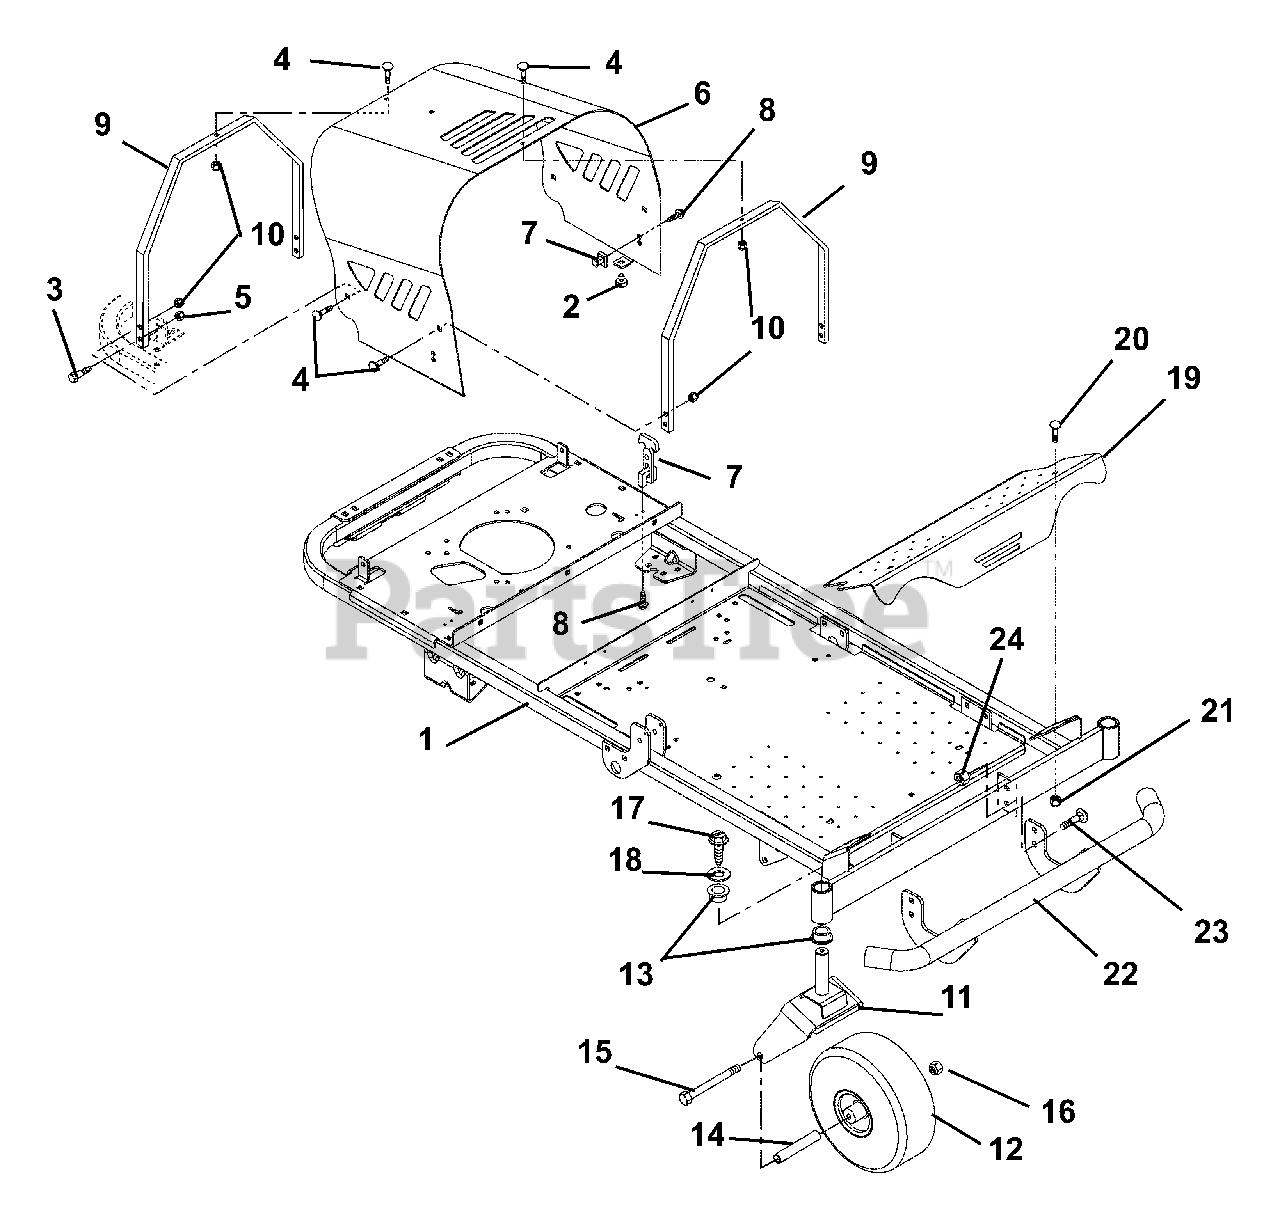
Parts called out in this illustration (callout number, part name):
1	Weldment, Fixed Axle Frame
2	Button Bumper
3	Bolt, Shoulder .375-16 x .135
4	Bolt, Round Head Square Neck .31-18 x .62
5	Nut, Locking Top Flange .38-16
6	Hood, Zoom
7	Latch, Rubber
8	Screw-Machine 10-24 x .50 Hex Washer Head
9	Brace, Hood
10	Nut, Locking Top Flange .31-18
11	Fork, Caster
12	Assembly, Tire 4 x 11- 2 Ply
13	Bushing, Flange 1.00 x 1.25 x 1.50 x 1.50
14	Spacer, Wheel
15	Bolt, Hex .50-13 x 6.50 Grade 5
16	Nut, Locking Top Flange .50-13
17	Screw, Tapping .38-16 x 1.25 Hex Washer Head
18	Washer, Flat Steel .38 x 1.50 x .125
19	Foot Rest
20	Bolt, Round Head Square Neck .38-16 x 1.00 Grade 5
21	Nut, .38-16 Flange Nyloc
22	Bumper, Zoom
23	Bolt, Round Head Square Neck .38-16 x 1.00 Grade 5
24	Nut, .38-16 Flange Nyloc
